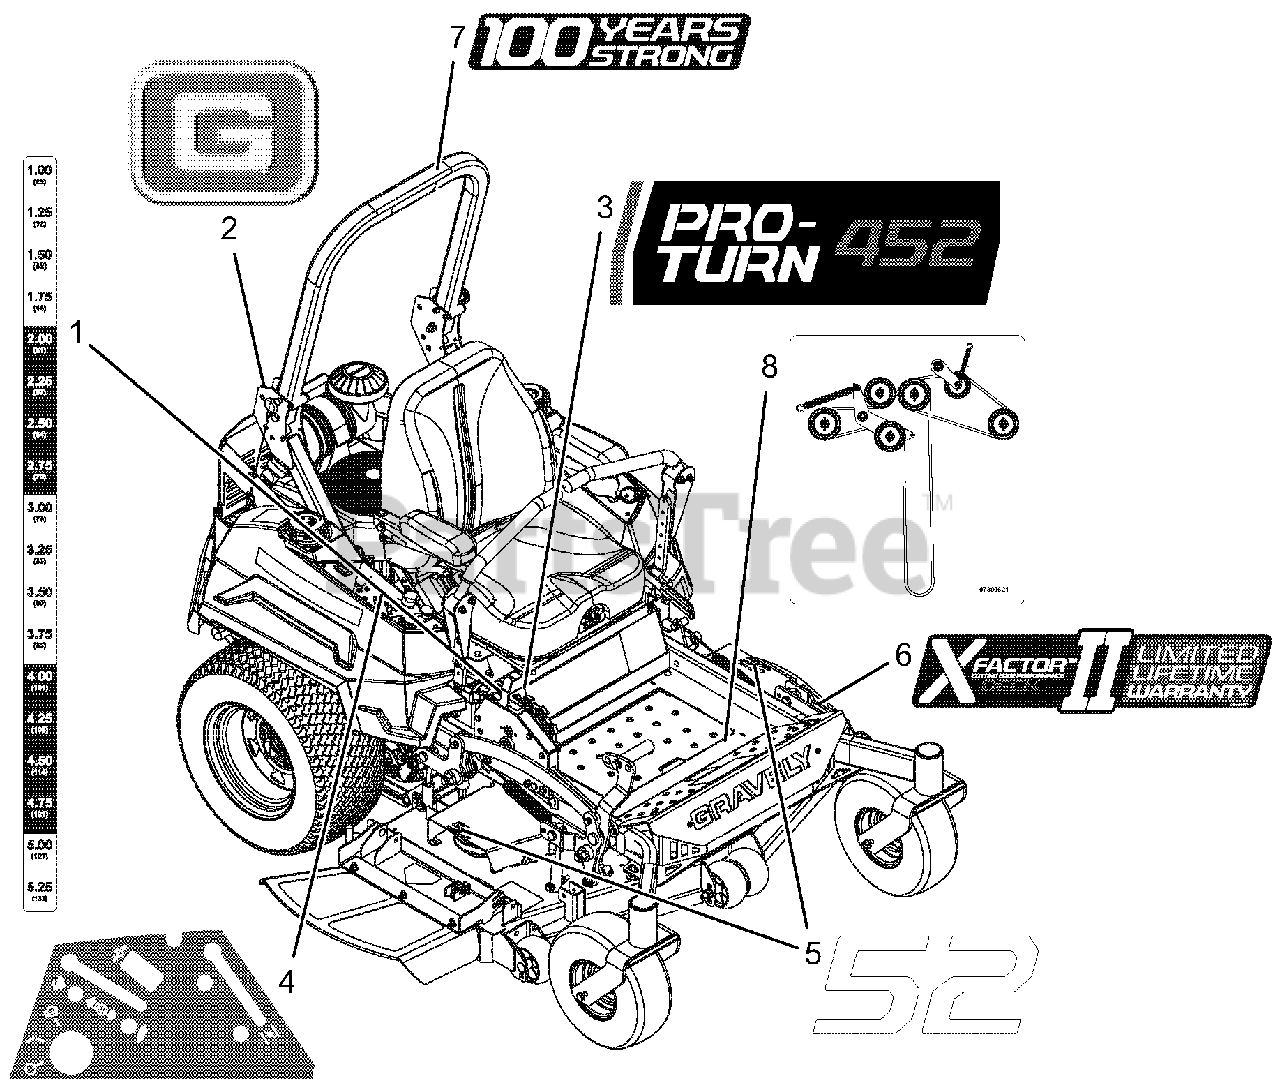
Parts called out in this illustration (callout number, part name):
1	DECAL, PT400 HEIGHT OF CUT
2	DECAL, GRAVELY BRAND
3	DECAL, PRO-TURN 452
4	DECAL, NON-EFI CONTROL PANEL
5	DECAL, 52"
6	DECAL, X-FACTOR DECK
7	DECAL, GRAVELY 100 YR
8	DCL,BELT ROUTE-RH V-SIDE IDLER
